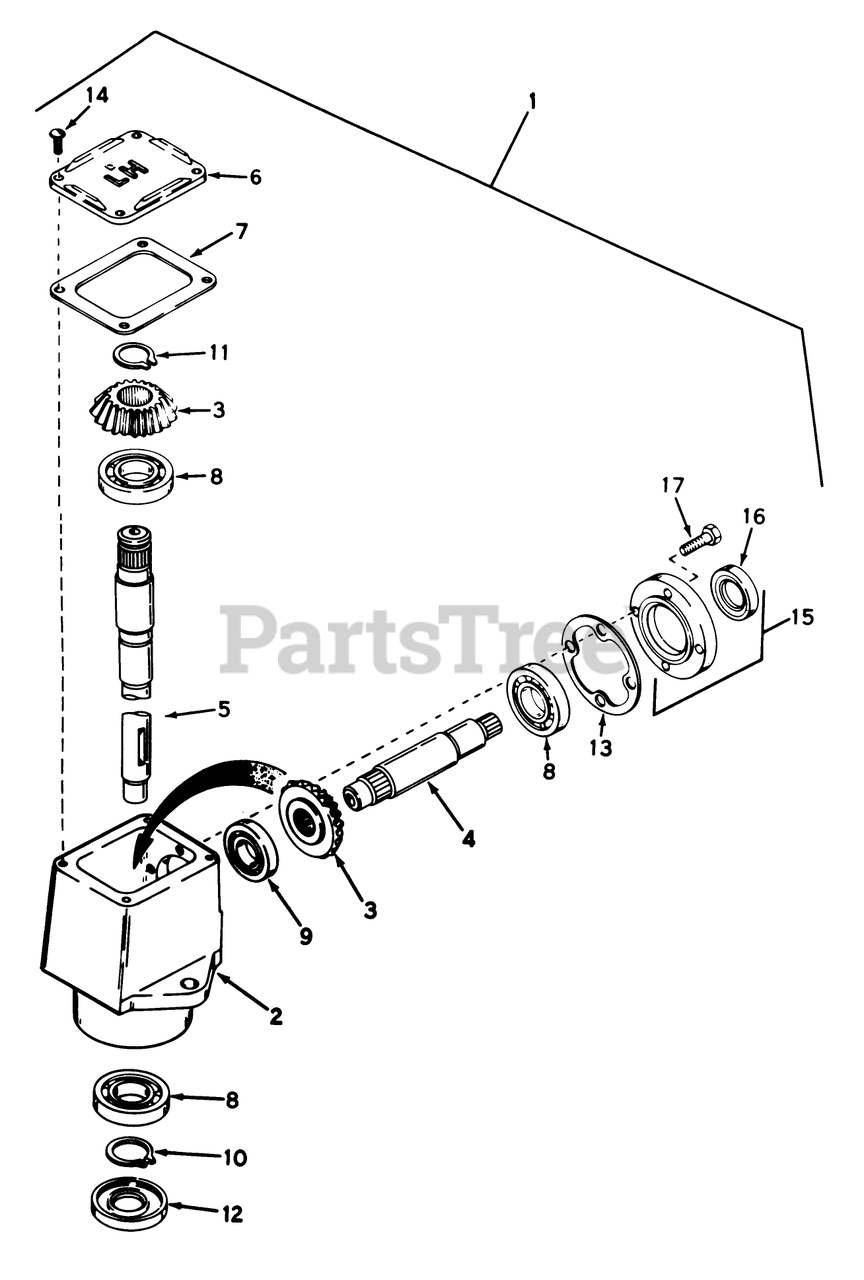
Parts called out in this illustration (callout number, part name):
1	Head Assembly-Left Hand (Incl. Ref. #2-15)
2	Housing
3	Bevel Gear
4	Shaft-Input
5	Shaft-Output
6	Cover
7	Gasket
8	Bearing
9	Bearing
10	Ring-Snap
11	Ring-Snap
13	Gasket
14	Screw
15	Retainer Asm
16	Oil Seal
17	Ring Set (STD)
